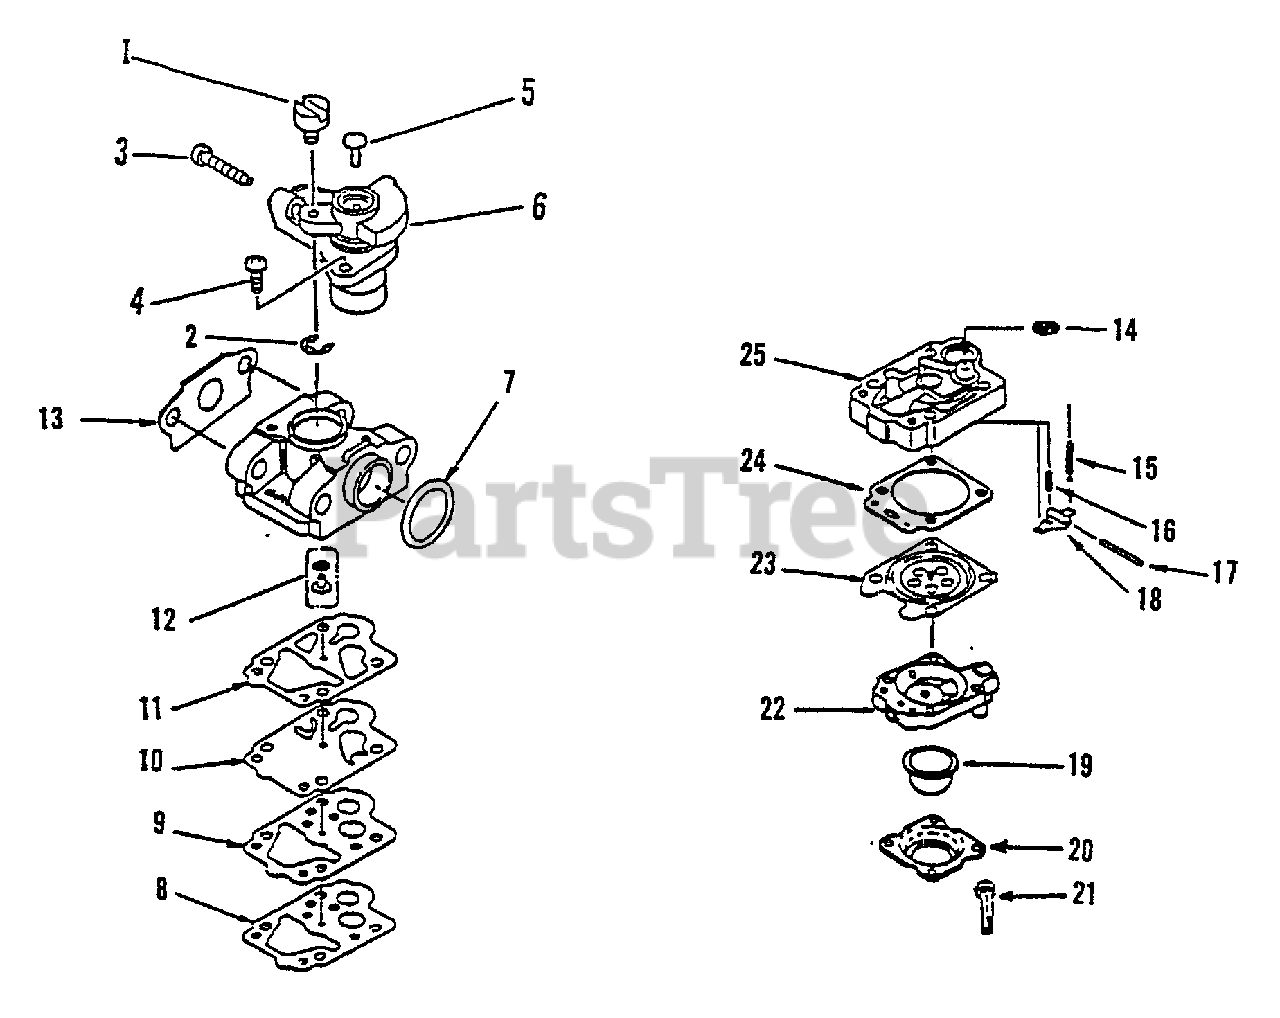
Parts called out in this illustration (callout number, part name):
2	RING, RETAINING
3	SCREW, IDLE ADJUST
5	PLUG, WELCH
6	THROTTLE VALVE ASSY
7	RING, MOUNTING
8	GASKET, PLATE
9	PLATE, PUMP
10	DIAPHRAGM, PURGE
11	GASKET, PURGE
12	MAIN JET KIT
13	GASKET, FLANGE
14	STRAINER
15	VALVE, INLET NEEDLE
16	SPRING, METERING LEVER
17	PIN, METERING LEVER
18	LEVER, METERING
19	BULB, PURGE
20	RETAINER, PURGE BULB
22	BASE, PURGE
23	DIAPHRAGM, METERING
24	GASKET, METERING
25	BASE, PURGE
